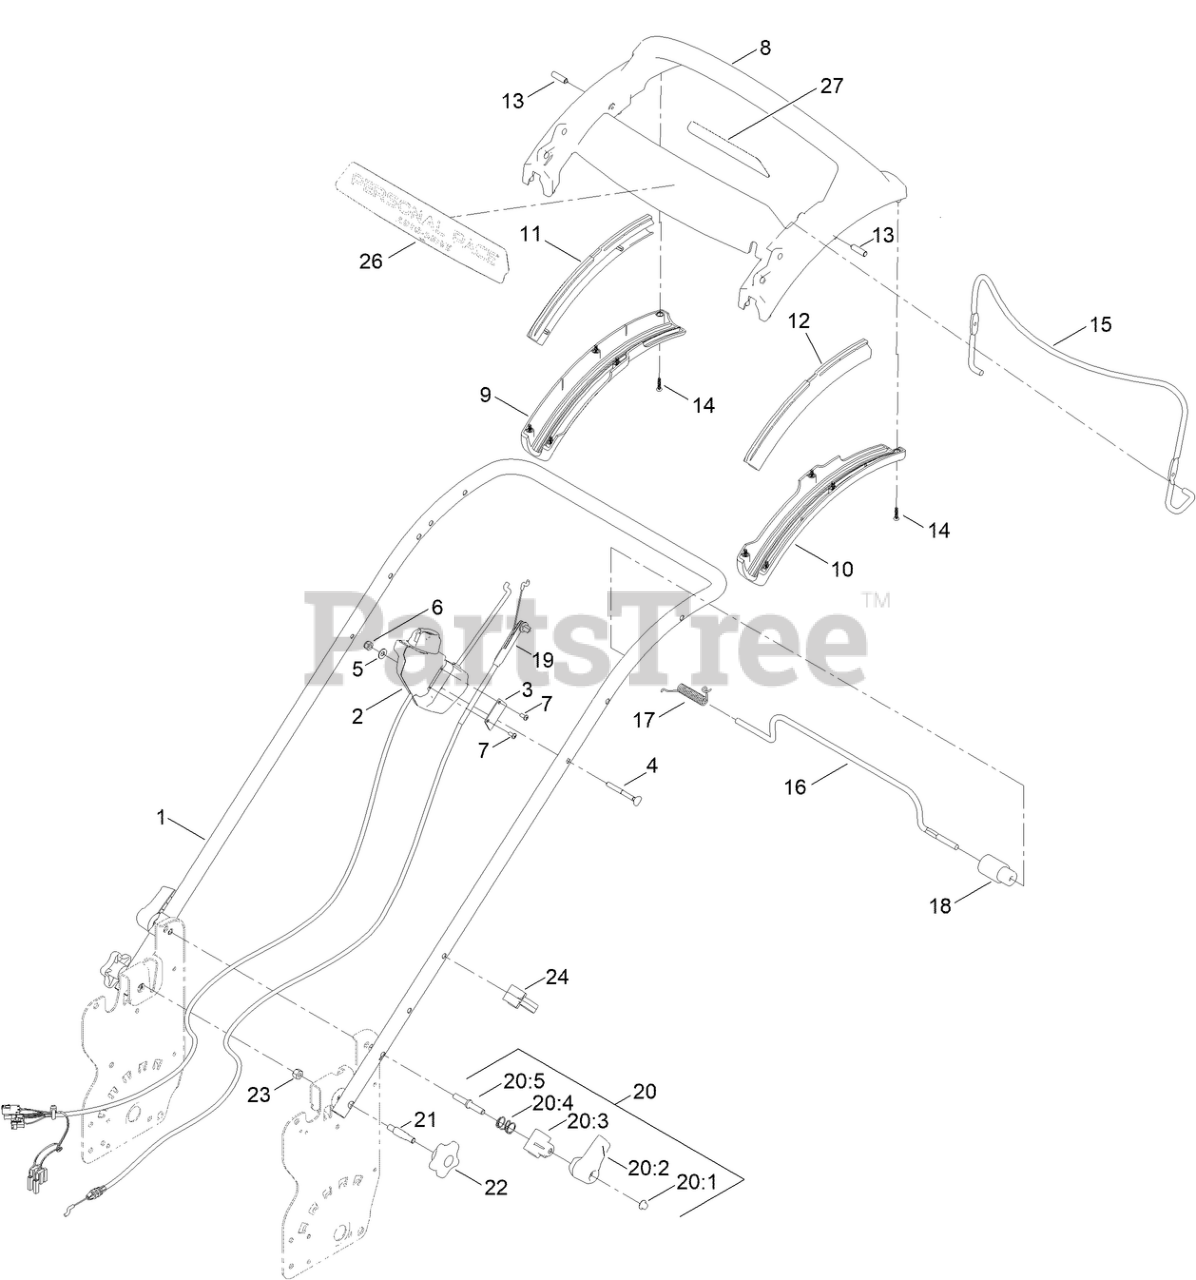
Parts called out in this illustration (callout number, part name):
1	HANDLE-CURVED
2	ASM-SWITCH, EPP
3	TAB-RETENTION, BAIL
4	SCREW-HANDLE
5	WASHER-FLAT
6	NUT-LOCK, NI
7	SCREW-PPH
8	HANDLE-PERSONAL PACE, CURVED
9	BOTTOM-HANDLE, RH
10	BOTTOM-HANDLE, LH
11	GUIDE-CURVED, RH (EPP)
12	GUIDE-CURVED, LH (EPP)
13	PIN-HANDLE, PP
14	SCREW-PPH
15	BAIL-BRAKE
16	ROD-CONTROL, TRACTION
17	SPRING-TORSION
18	LEVER-TRACTION, PM
19	CABLE-BRAKE, PP BS
20	QUICK RELEASE ASM
20:1	NUT-PUSH
20:2	LEVER-RELEASE
20:3	ANCHOR-SPRING
20:4	SPRING-COMPRESSION
20:5	ROD-RELEASE
21	BOLT-SHOULDER, HANDLE
22	KNOB-HANDLE
23	NUT-LOCK, NI
24	GUIDE-CABLE
26	DECAL-HANDLE, PP
27	DECAL-EPP
